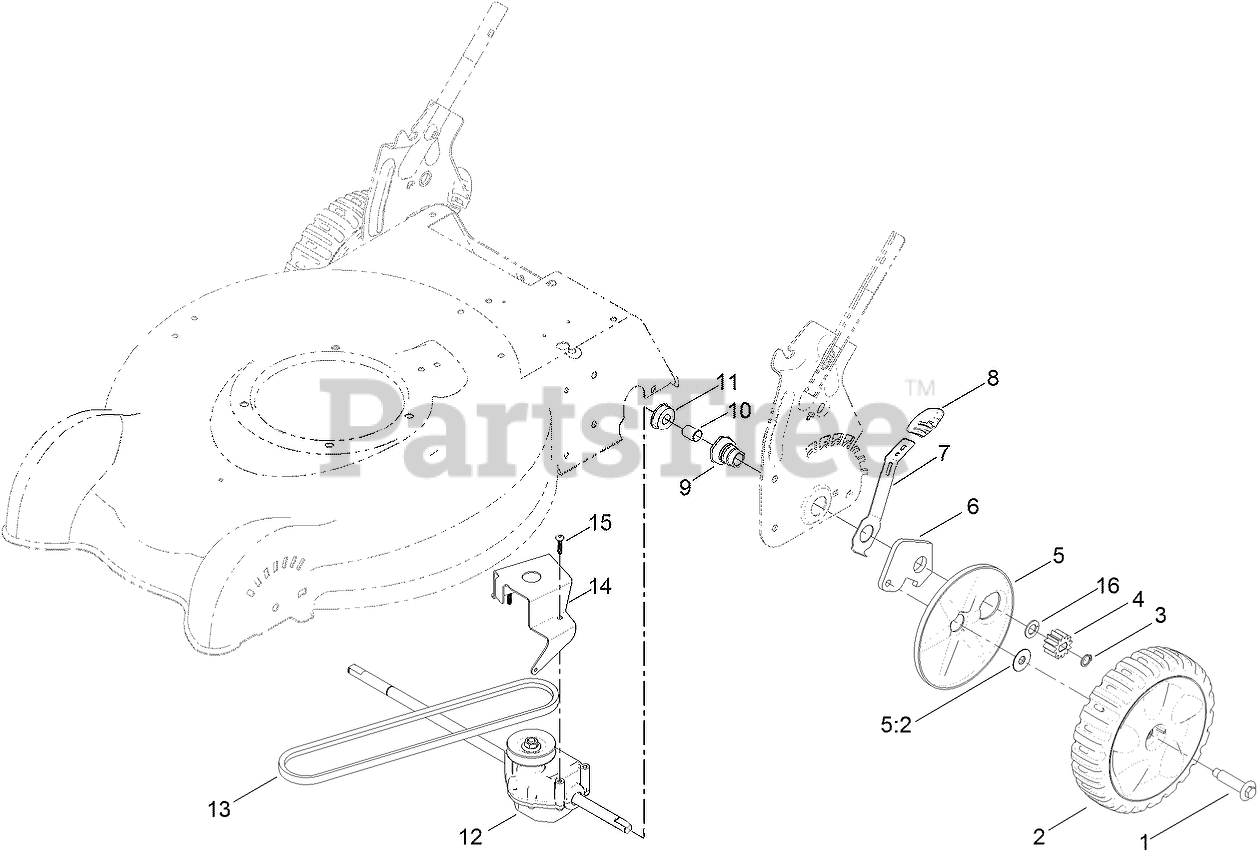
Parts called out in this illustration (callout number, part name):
1	BOLT-SHOULDER
2	8 INCH WHEEL AND GEAR ASM
3	RING-RETAINING
4	GEAR-PINION
5	WHEEL COVER ASM
5:2	WASHER-STEPPED
6	ARM-PIVOT, REAR
7	ARM-SPRING
8	Knob-Lever, HOC
9	RETAINER-BUSHING, HOC
10	BUSHING-SLEEVE
11	BEARING-BALL
12	TRANSMISSION ASM
13	V-BELT
14	BRACKET-TRANSMISSION
15	SCREW-PLASTITE
16	WASHER-THRUST
